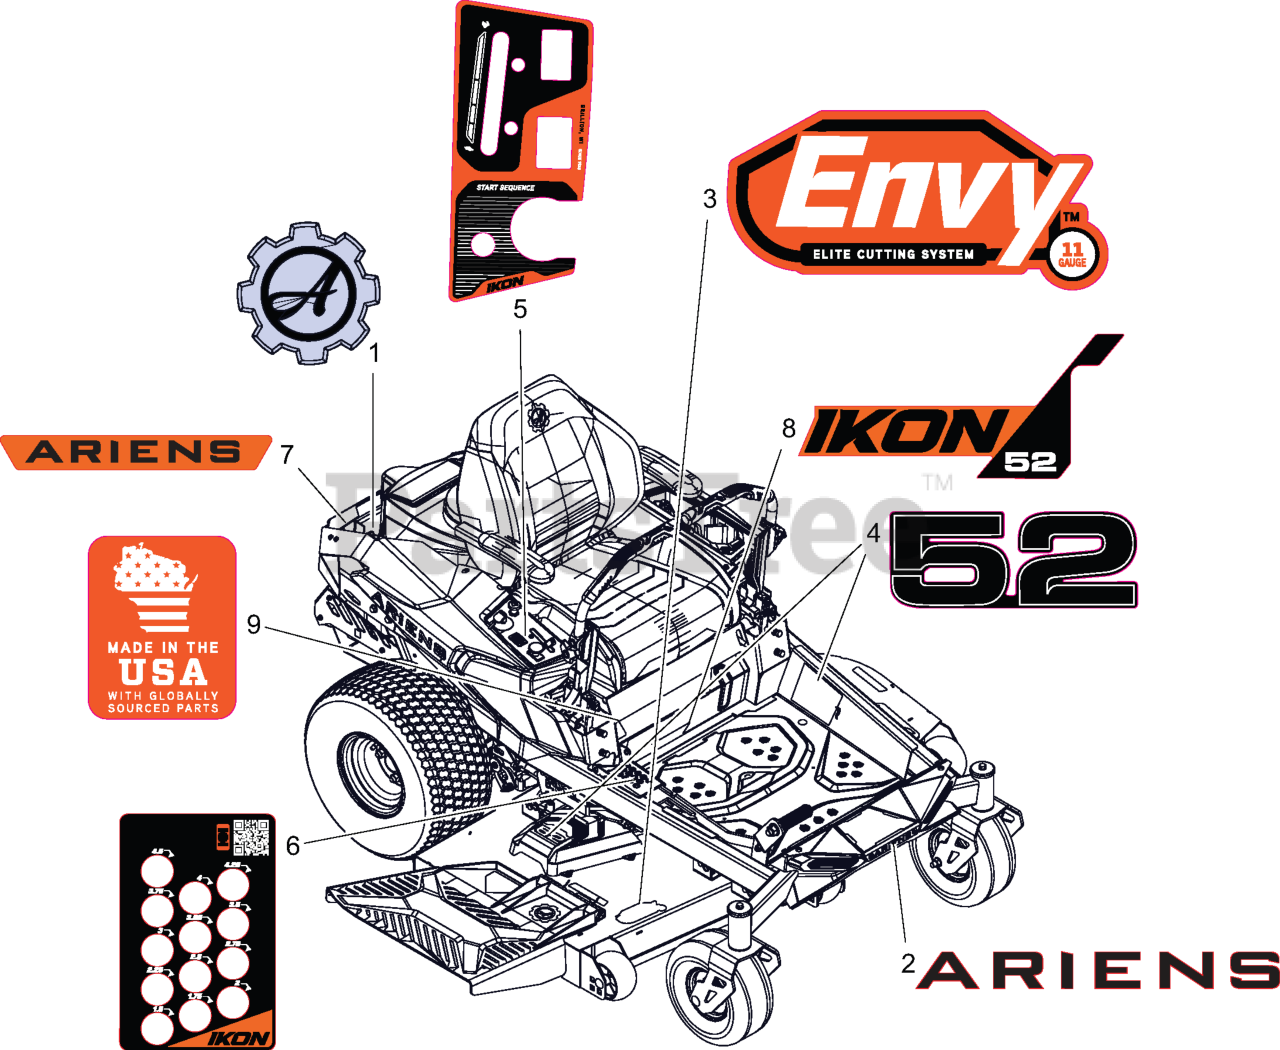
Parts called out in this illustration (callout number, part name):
1	DECAL- ARIENS GEAR BADGE
2	DECAL- ARIENS-BADGE
3	DECAL- DECK
4	DECAL- 52
5	DECAL- CONTROL PANEL
6	DECAL- HEIGHT OF CUT
7	DECAL- ARIENS
8	DECAL- IKON 52 KICKPLATE
9	DECAL- MADE IN USA
